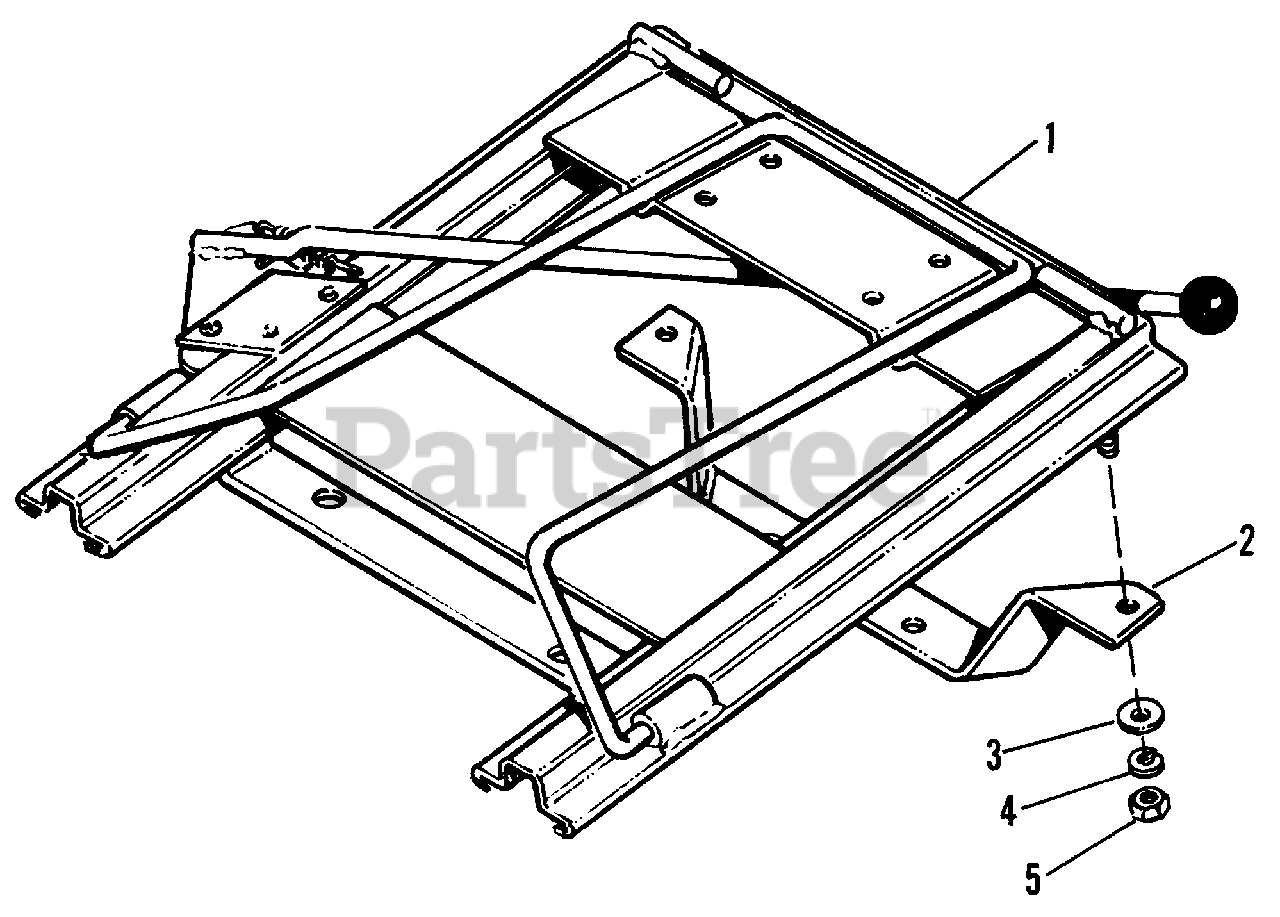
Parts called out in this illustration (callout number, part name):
1	Seat Adjuster
2	Seat Support
3	Plain Washer, 5/16"
4	Lock Washer, 5/16"
5	Hex Nut, Full, 5/16"-18
